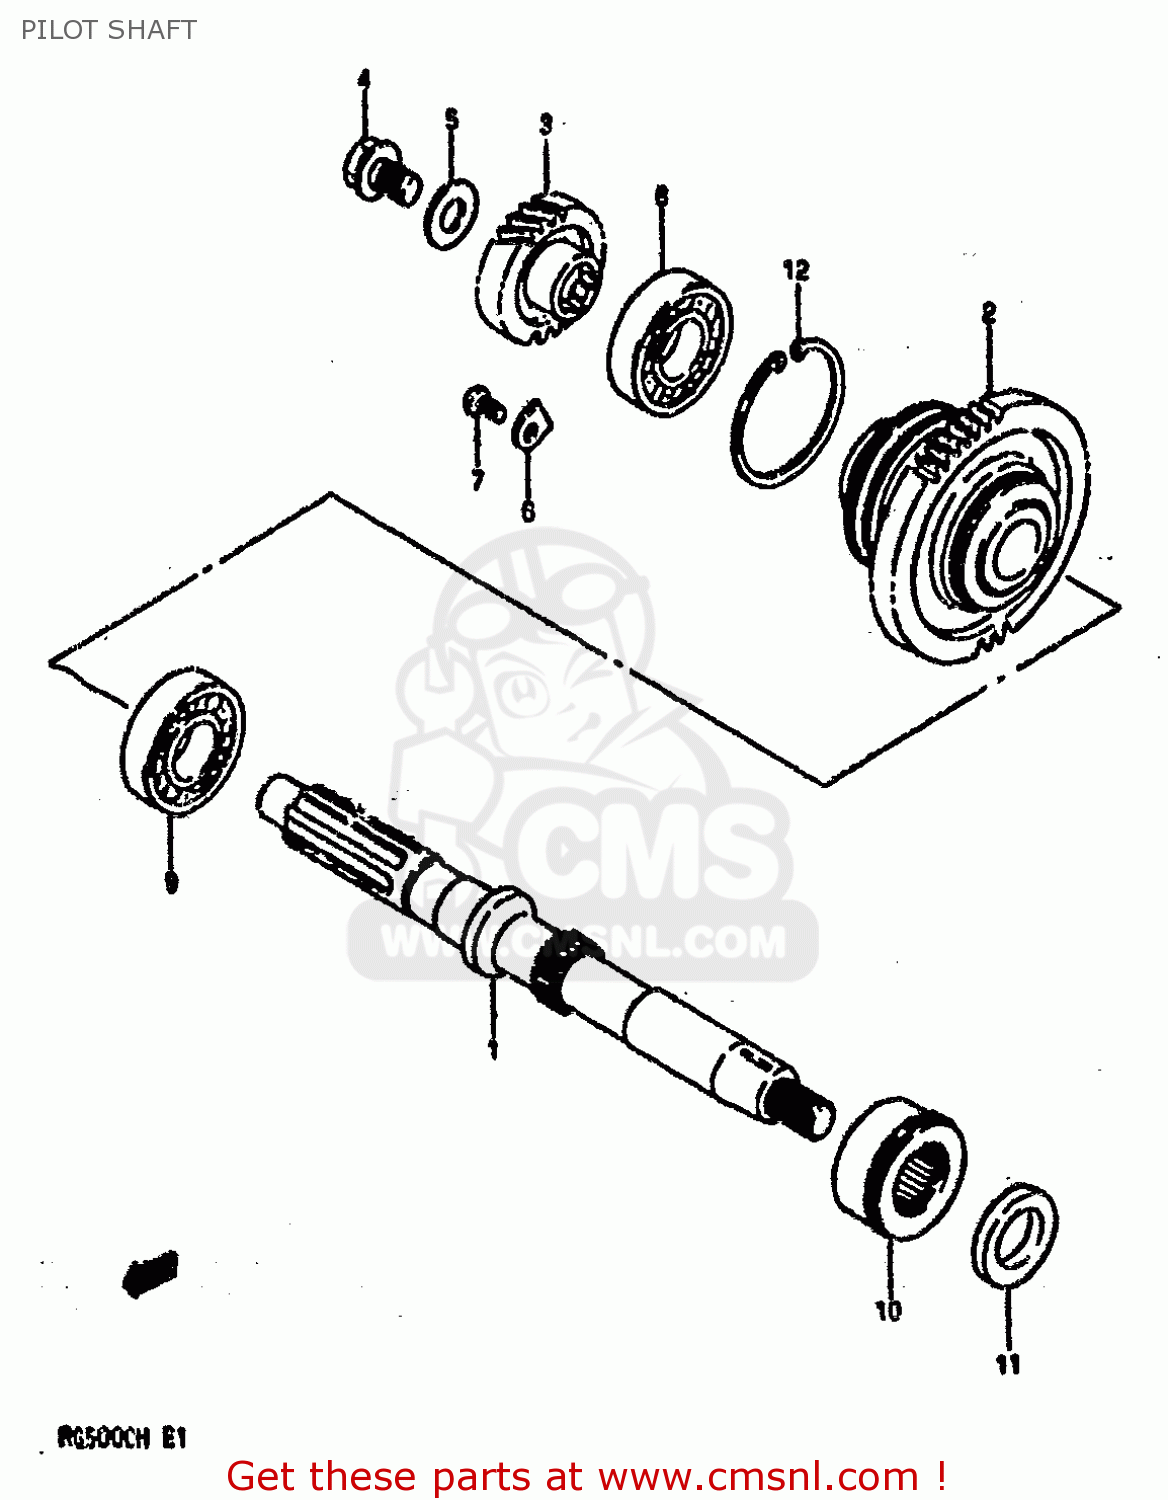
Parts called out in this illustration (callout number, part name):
1	SHAFT,PILOT
2	GEAR,PILOT DRIVEN
3	GEAR,PRIMARY DRIVE (NT:26)
4	BOLT,PILOT SHAFT
5	WASHER
6	RETAINER
7	SCREW 6X12
8	BEARING
9	BEARING(22X50X14)
10	BEARING(22X32X21.5)
11	SEAL,OIL(22X33X7)
12	CIRCLIP
